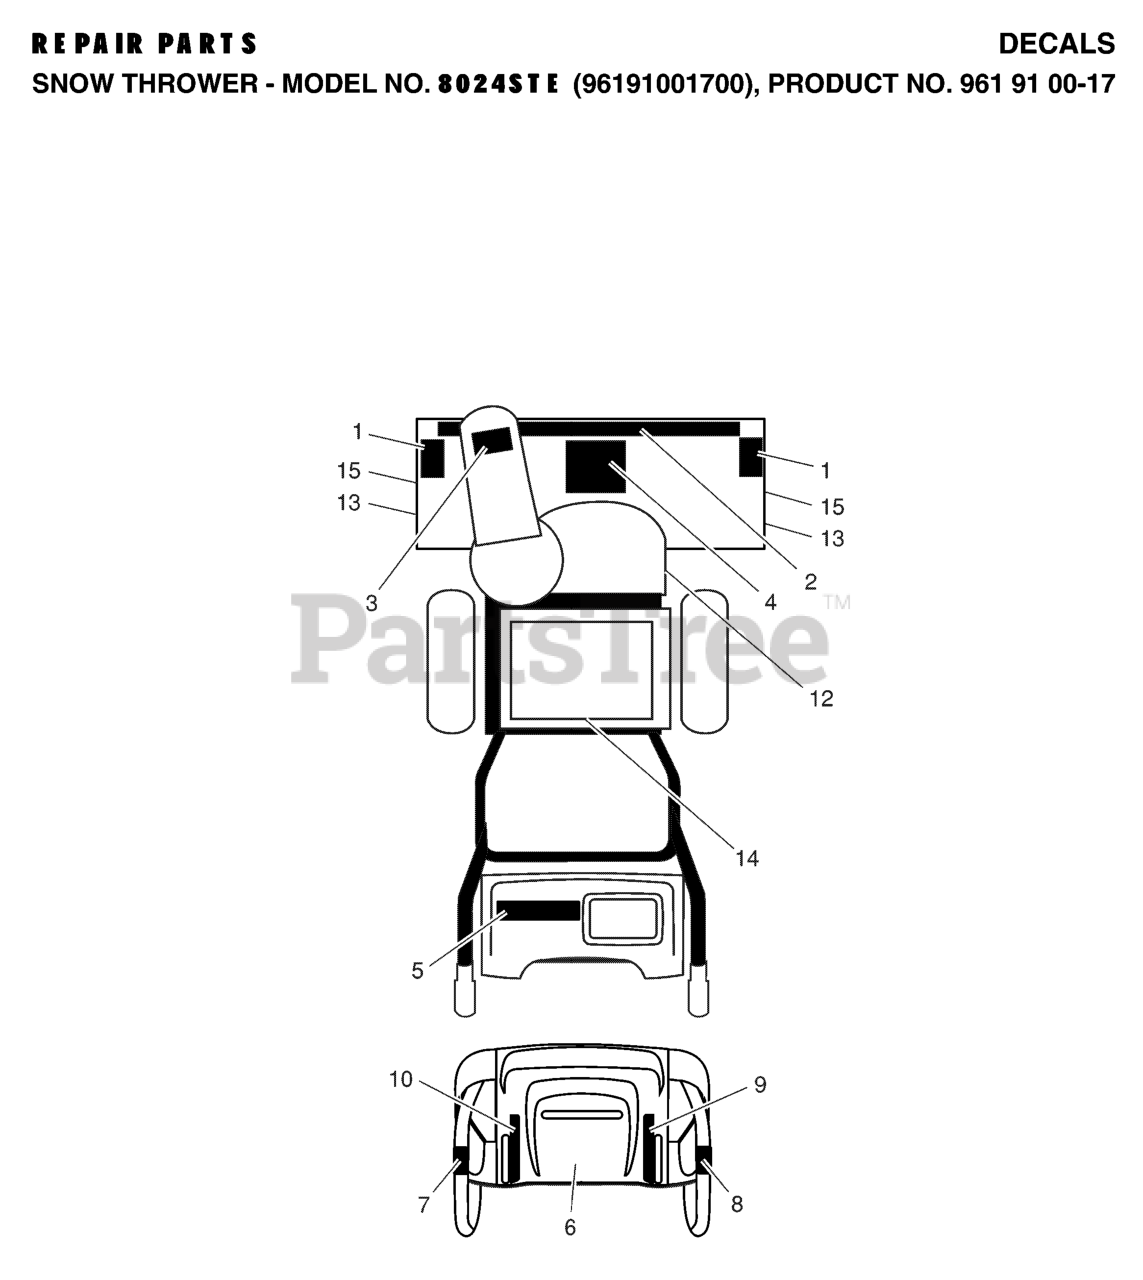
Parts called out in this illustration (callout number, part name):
1	DECAL.AUGER.SAFETY.
3	DECAL.CHUTE.SAFETY.
4	DECAL.AUGER."
6	DECAL.CONSOLE.INSTRUCTION
10	DECAL.REM.DEFLECTOR.LT
12	DECAL.BELT.GUARD.
14	DECAL.FENDER
15	DECAL, HUSQVARNA
